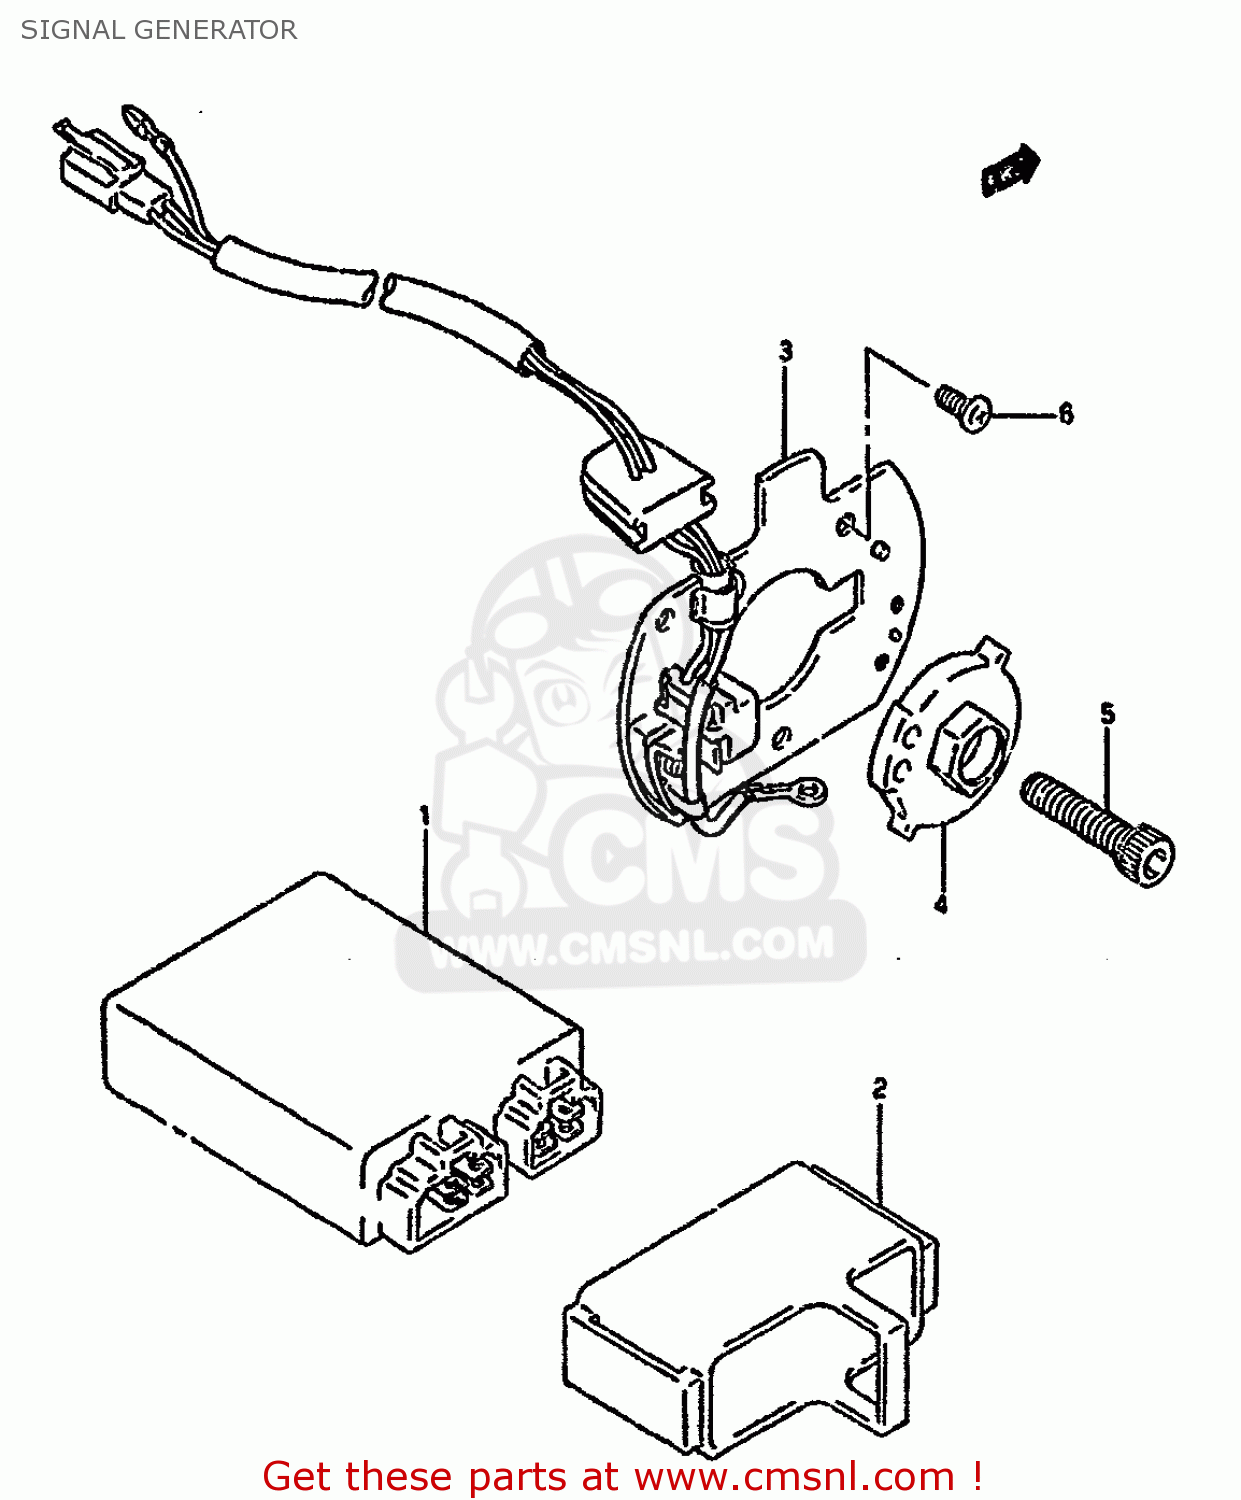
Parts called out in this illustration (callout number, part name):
1	IGNITER ASSY
2	CUSHION,IGNITER
3	GENERATOR ASSY,SIGNAL
4	ROTOR,SIGNAL
5	BOLT
6	SCREW
